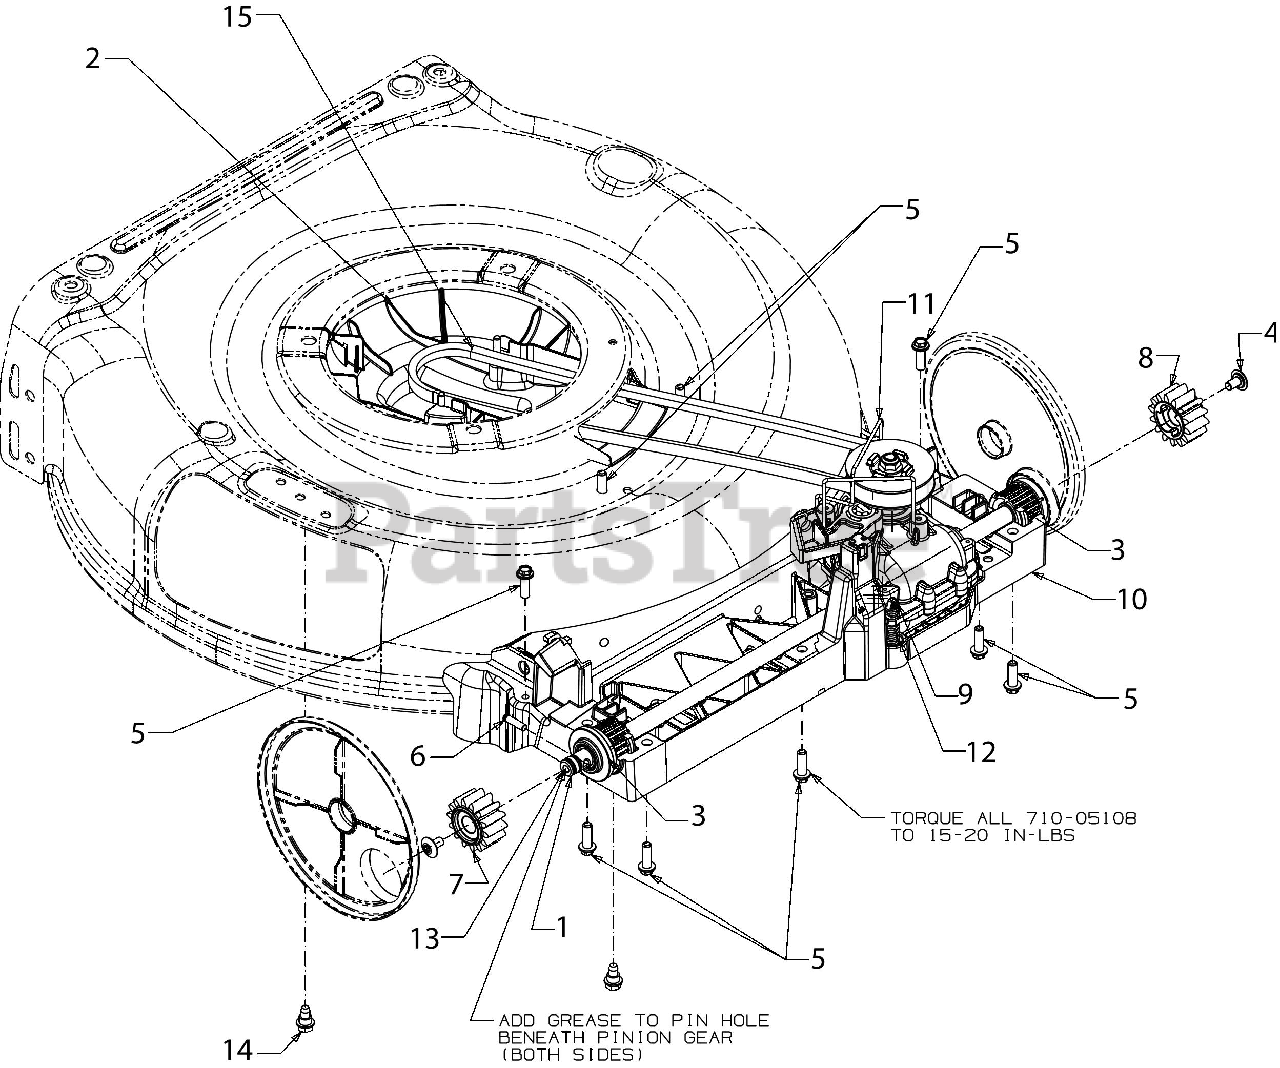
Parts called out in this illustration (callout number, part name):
1	FORWARD TRANSMISSION ASSEMBLY
1	SCREW .159 x .610
1	SCREW .159 x .43
1	INPUT WORM SHAFT
1	FLANGE LOCK NUT 5/16-18
1	SPRING PIN1/8 x .812
1	FLAT WASHER
1	FLAT WASHER .508X1.000X.040
1	FLAT WASHER .510X1.000X.060
1	BALL BEARING
2	ENGINE BAFFLE ASSEMBLY
3	SPHERICAL BEARING ASSEMBLY
3	SLEEVE BEARING
4	SCREW 1/4-20 x .39
5	SCREW 1/4 x .750
7	SPUR GEAR 14T R
8	SPUR GEAR 14T L
9	SPRING COMPRESSION
10	LOWER TRAY
11	TRANSMISSION WIRE
12	COMPRESSION SPRING
13	GREASE (NOT SERVICEABLE)
14	SHOULDER SCREW 1/4-20 x .50
15	V-BELT 3L x 34.18
